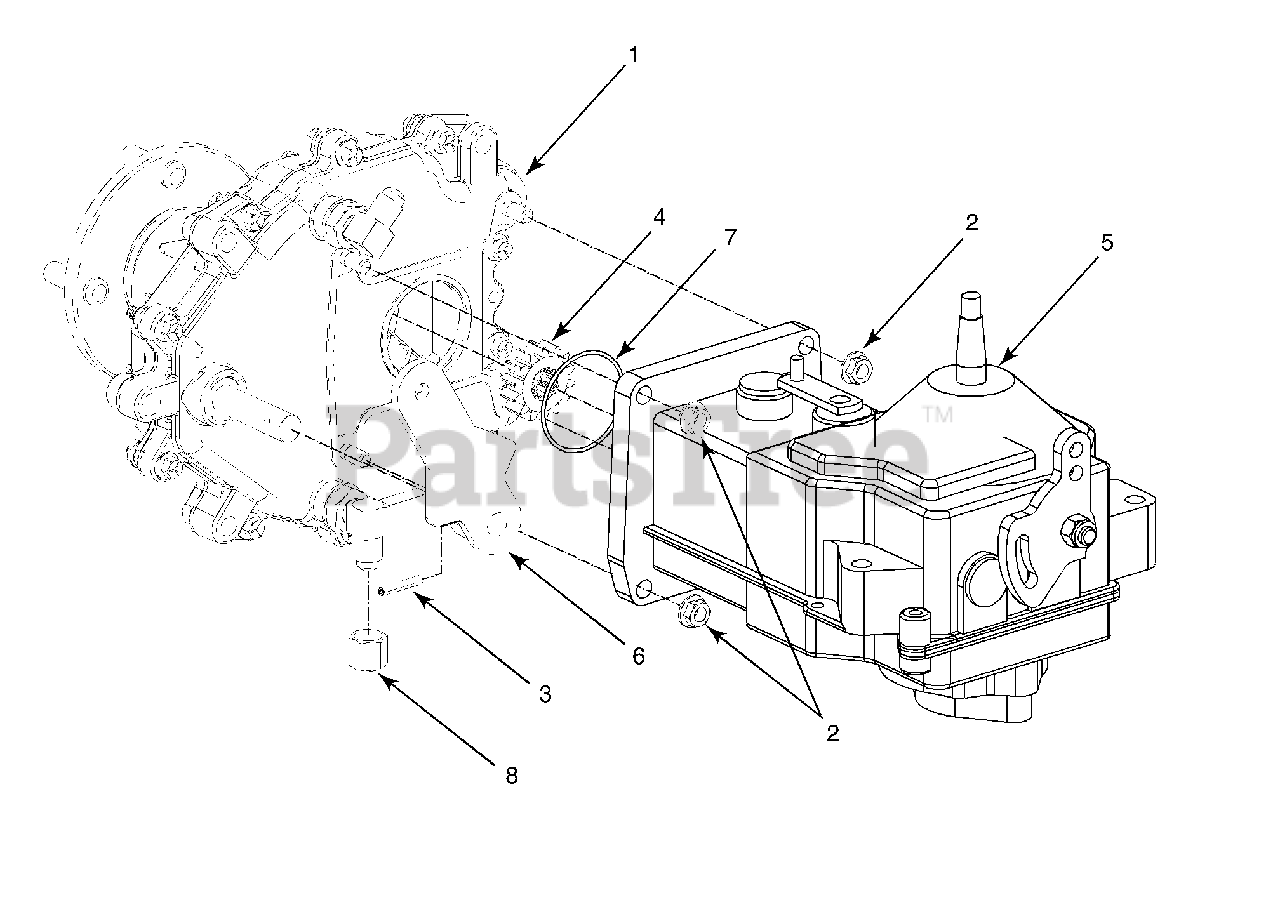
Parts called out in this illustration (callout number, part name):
1	Drive Ass'y, Complete Final
2	Nut, Hex Flange Lock, 5/16-18 GR5
3	Pin, Spirol, 3/16 x 1.0 HD
4	Gear, Spur, 14T
5	Transmission, Hydro: BDR
6	Lever, Park Brake
7	O-Ring, 2.0 Dia.
8	Nut, Cap, 3/8
